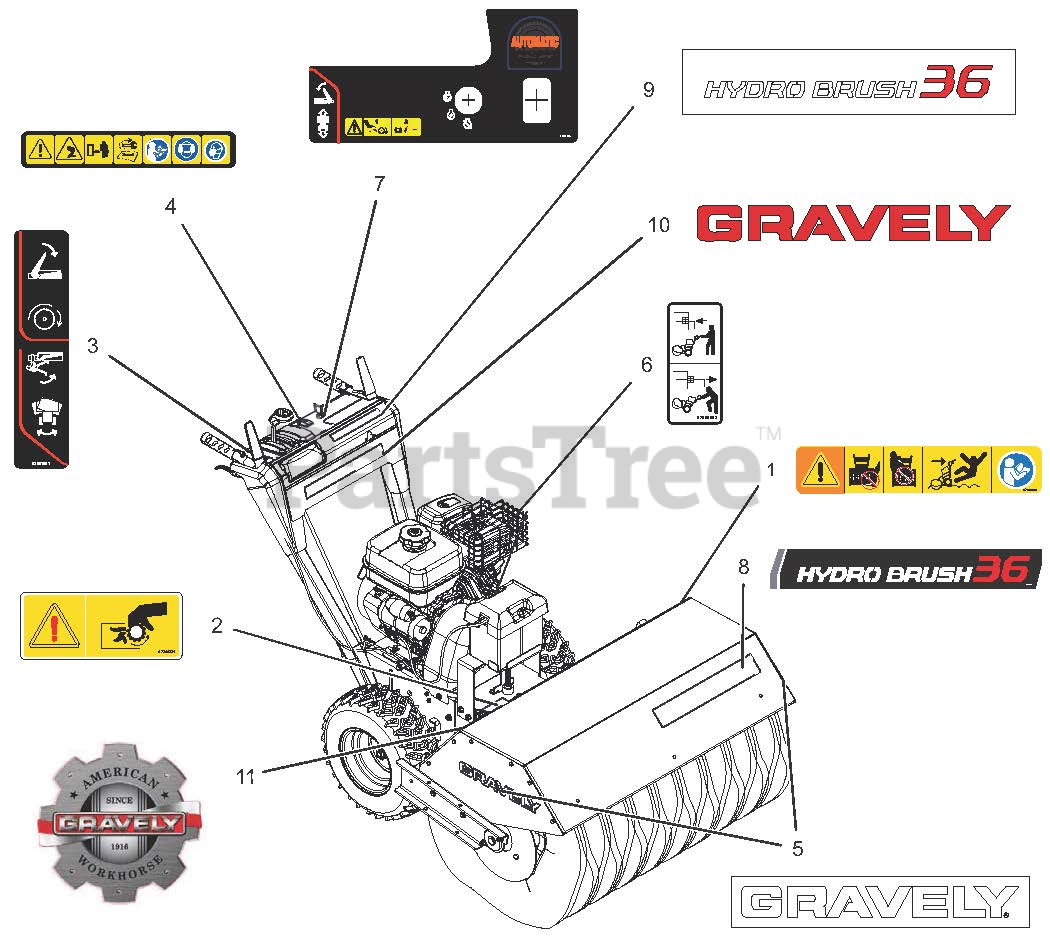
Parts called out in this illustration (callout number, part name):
1	DECAL, DANGER -POWER BRUSH-CE
2	DECAL, PTO WARNING
3	DECAL,CONTROL,BRUSH,RH
4	DECAL, SAFETY, DASH, BRUSH
5	DECAL, 13.5" GRAVELY LOGO
6	DECAL, HYDRO BRUSH BYPASS
7	DECAL,CNTRL,LRG BRUSH,LH,HYDRO
8	DECAL,HYDRO BRUSH 36,GRAVELY
9	DECAL,HYDRO BRUSH 36,GRAVELY
10	DECAL,GRAVELY,RED,13"
11	DECAL, GRAVELY HERITAGE-LARGE
